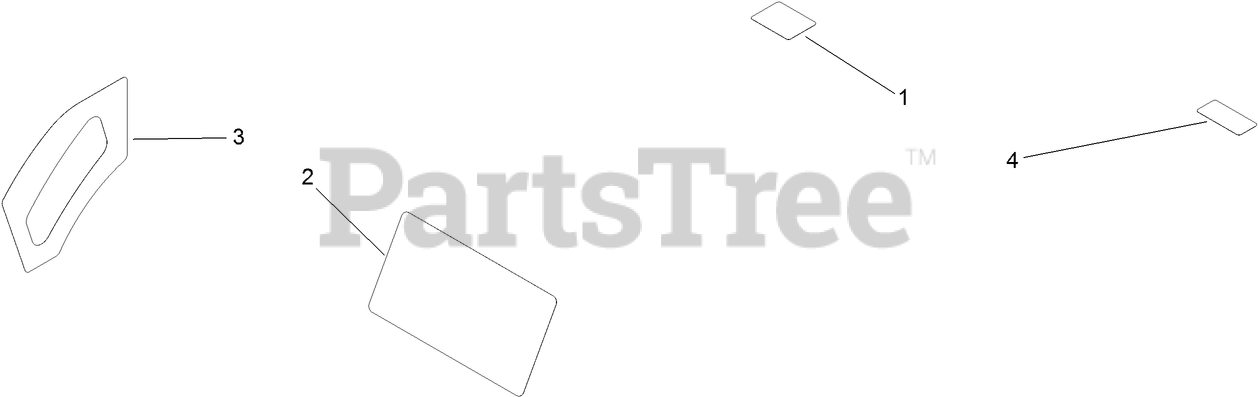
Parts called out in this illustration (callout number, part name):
1	DECAL-MAINTENANCE
2	DECAL-CONTROL, SPEED
3	DECAL-HOC
4	DECAL-LOCATION, SERVICE DEALER
